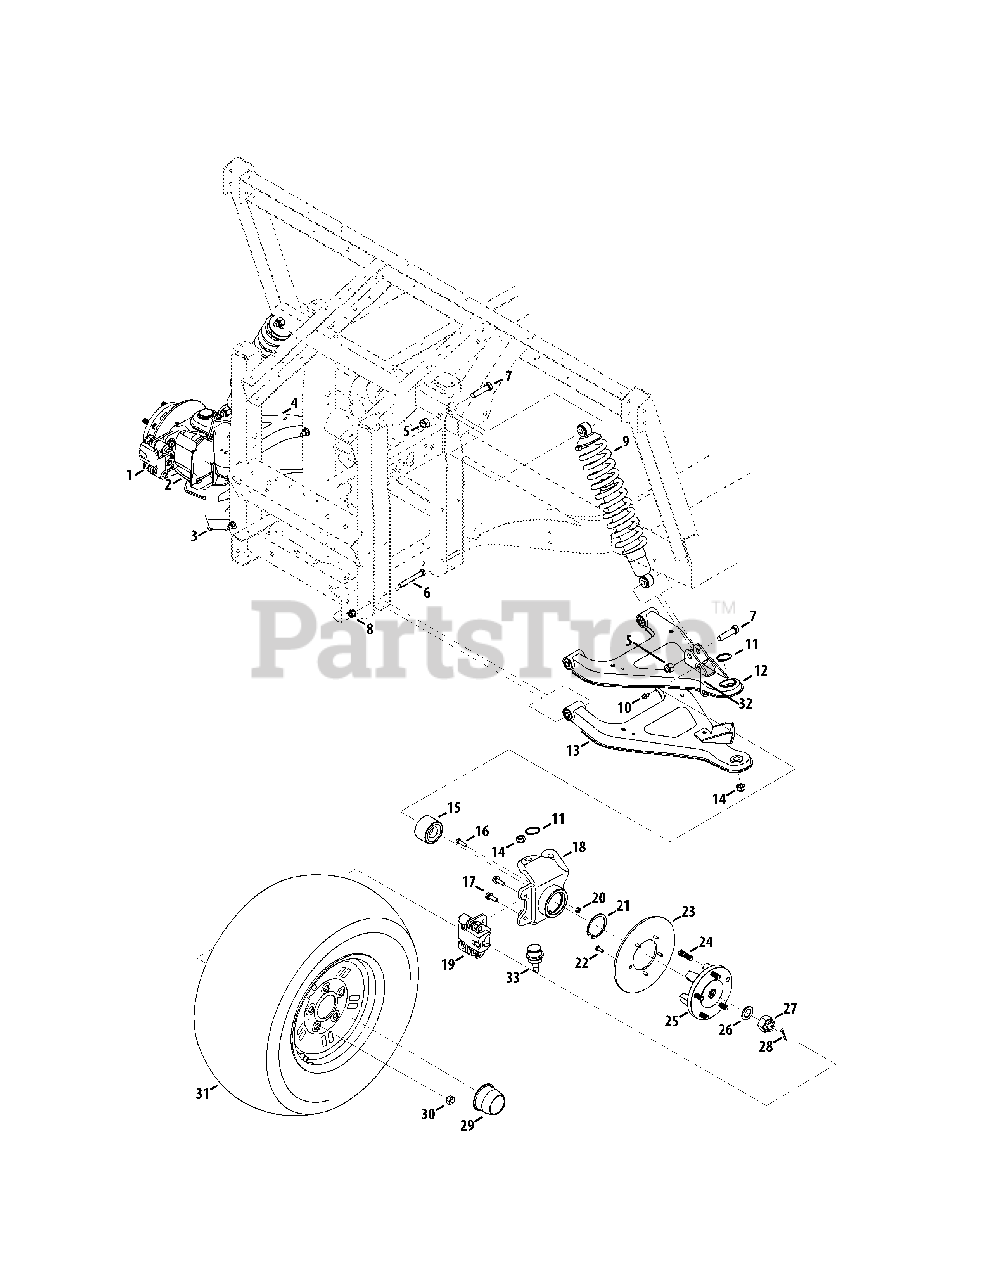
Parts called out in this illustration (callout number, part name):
1	Brake, hyd, caliper, frt, RH
2	Housing, knuckle, r/frt, mach
3	Control Assembly, r/frt, lwr
4	Arm Assembly, r/frt, upr
5	Nut, Hex Lock, 1/2-13, Nylon
6	Screw, 3/8-16, 3.00, gr8, std
7	Screw, 1/2-13, 2.00, gr5, std
8	Nut, Flange Lock, 3/8-16, Nylon
9	Shabs, 5.0 Stroke, frt
10	Screw, tt, 1/4-20x.500
11	Ring, Retainer, 34 x 1.6
12	Control Assembly, l/frt, upr
13	Control Assembly, l/ftr, lwr
14	Nut, Nylock, m12 x 1.25
15	Bearing, double Row, 60x30x37
16	Screw, 1/4-20 x 1.00,
17	Screw, m8-1.25, 25.00
18	Housing, knuckle, l/frt, mach
19	Brake, hydraulic, caliper, frt, LH
20	Nut, Hex,1/4-20
21	Ring, Retainer, dho-60
22	Screw, 1/4-20, .625, gr5, lock
23	Disc, brake, 8.00x.188
24	Stud, rib Neck, 7/16-14 x 1.6
25	Hub, wheel
26	Washer, flat, .88 x 1.38 x .125, ht
27	Nut, slotted, 22x1.5
28	Pin, cotter, 5/32, 1.25
29	Cap, Wheel UV
30	Nut, lug, 7/16-14
31	Wheel Assembly, 25 x 10-12
31	Tire Only, 25 x 10.5-12
32	Wire, Brake Line
33	Ball Joint, 14d-6201
